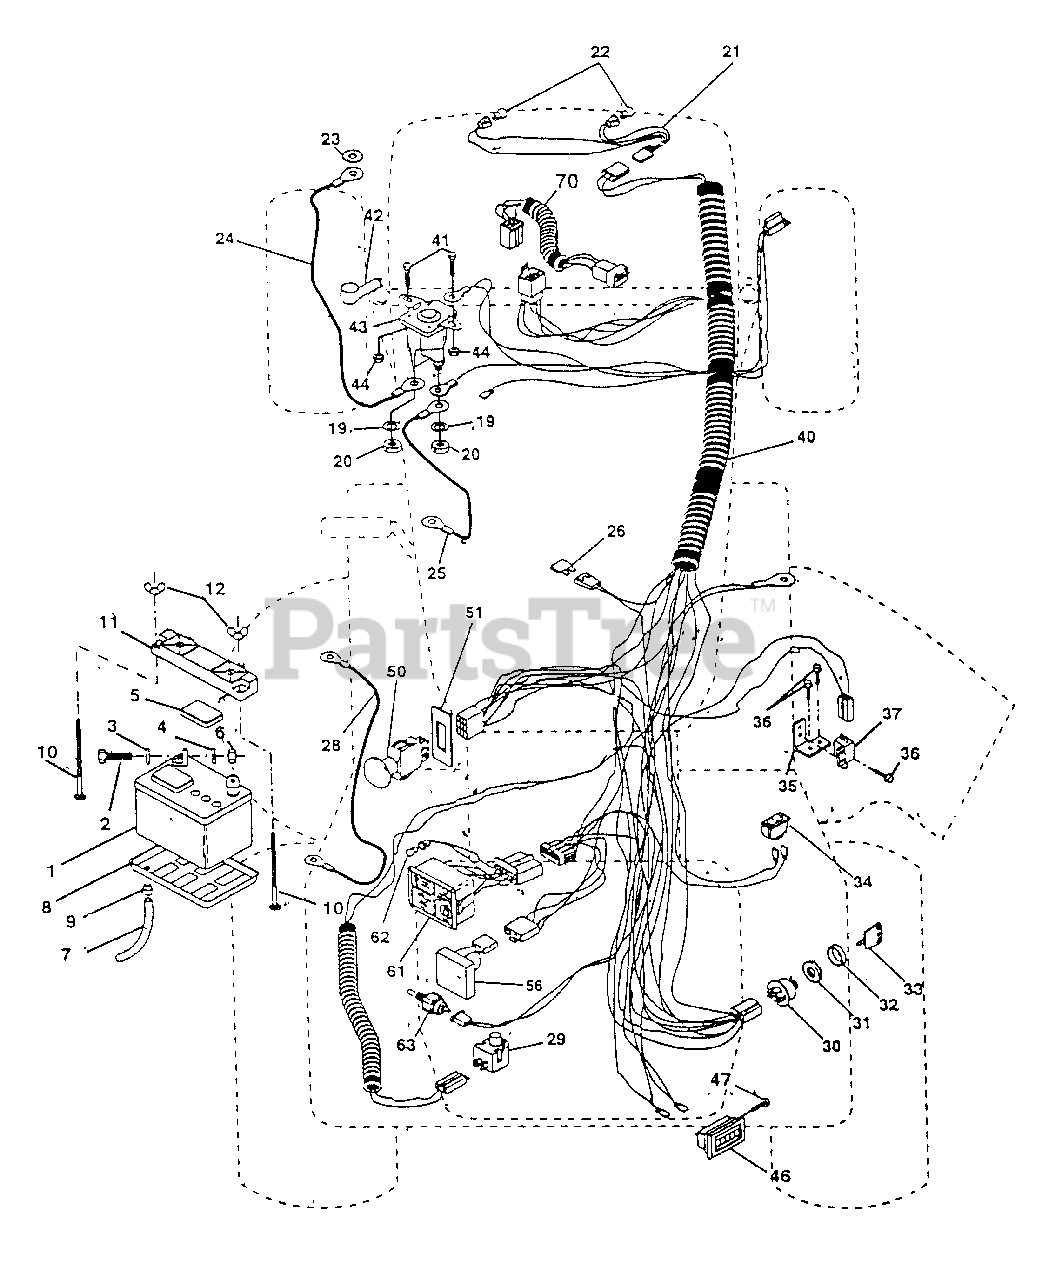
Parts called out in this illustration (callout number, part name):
1	Battery
2	Bolt, Hex Head 1/4-20 x 3/4
3	Washer 9/32 x 5/8 x 16 Gauge
4	Washer, Lock 1/4
5	Caps, Battery
6	Nut, Hex 1/4-20
7	Tube, Tray, Battery
8	Tray, Battery
9	Clamp, Hose
10	Bolt, Carriage 1/4-20 x 7-1/2
11	Guard, Terminal
12	Nut, Wing 1/4-20
19	Washer, Lock 1/4
20	Nut, Hex, Jam 1/4-20
21	Harness, Socket, Light
22	Bulb, Light
23	Washer, Lock, Internal Tooth 1/4
24	Cable, Battery (2)
25	Cable Starter 6 Ga. 11" Red
28	Cable, Battery
29	Switch, Plunger
30	Switch, Ignition
31	Nut, Ignition
32	Bezel, Ignition
33	Key, Molded
34	Switch, Light
35	Bracket Switch Interlock
36	Screw, Hex Tap #10-24 UNC
37	Switch, Clutch, Interlock
40	Harness, Ignition
41	Bolt, Hex 1/4-20 x 1/2 Grade 5
42	Cover, Terminal
43	Solenoid
44	Nut, Hex, Keps, 1/4-20
45	Adapter Ammeter Rectangular
46	Meter, Hour
47	Screw #10-24 x 1/2
50	Switch, P.T.O.
51	Ring, Retainer PTO
56	Sensor, Low Voltage
61	Package, Light
62	Bulb Dashboard Light 27 amp.
63	Wire Lead Sentry Kohler
70	Harness Eng. Koh. Tw 16 AR O Pump
